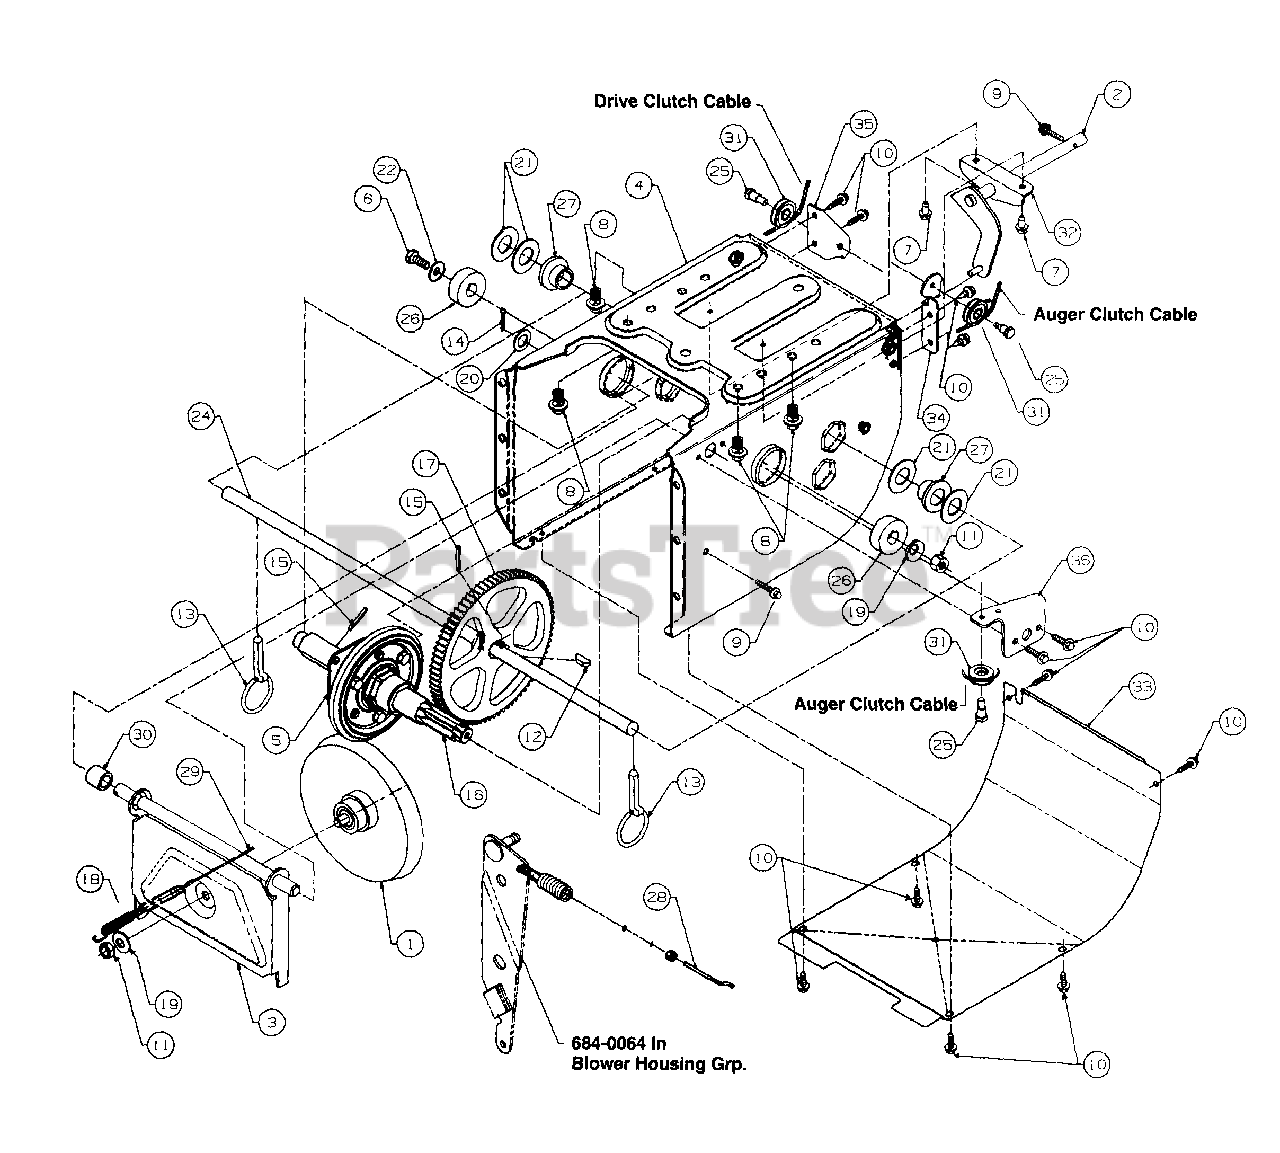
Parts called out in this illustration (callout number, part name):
1	Disc-Friction
6	Screw-Hex
7	Screw-Hex
8	Screw-Hex
9	Screw-Hex
10	Screw-Hex
11	Nut-Hex
12	Key-Hi Pro
13	Pin-Klick
14	Pin-Cotter
15	Pin-Roll
16	Shaft-Hex
17	Gear-80 Tooth
18	Spring
19	Washer-Bell
20	Washer-Flat
21	Washer-Flat
22	Washer-Bell
24	Axle (16" Wheel) 24.5" Lg.
25	Screw-Hex
26	Bearing-Ball
27	Bearing-Flange
28	Cable-Auger 44.75" Lg.
29	Cable-Auger 39.88" Lg.
30	Spacer
31	Roller-Cable
